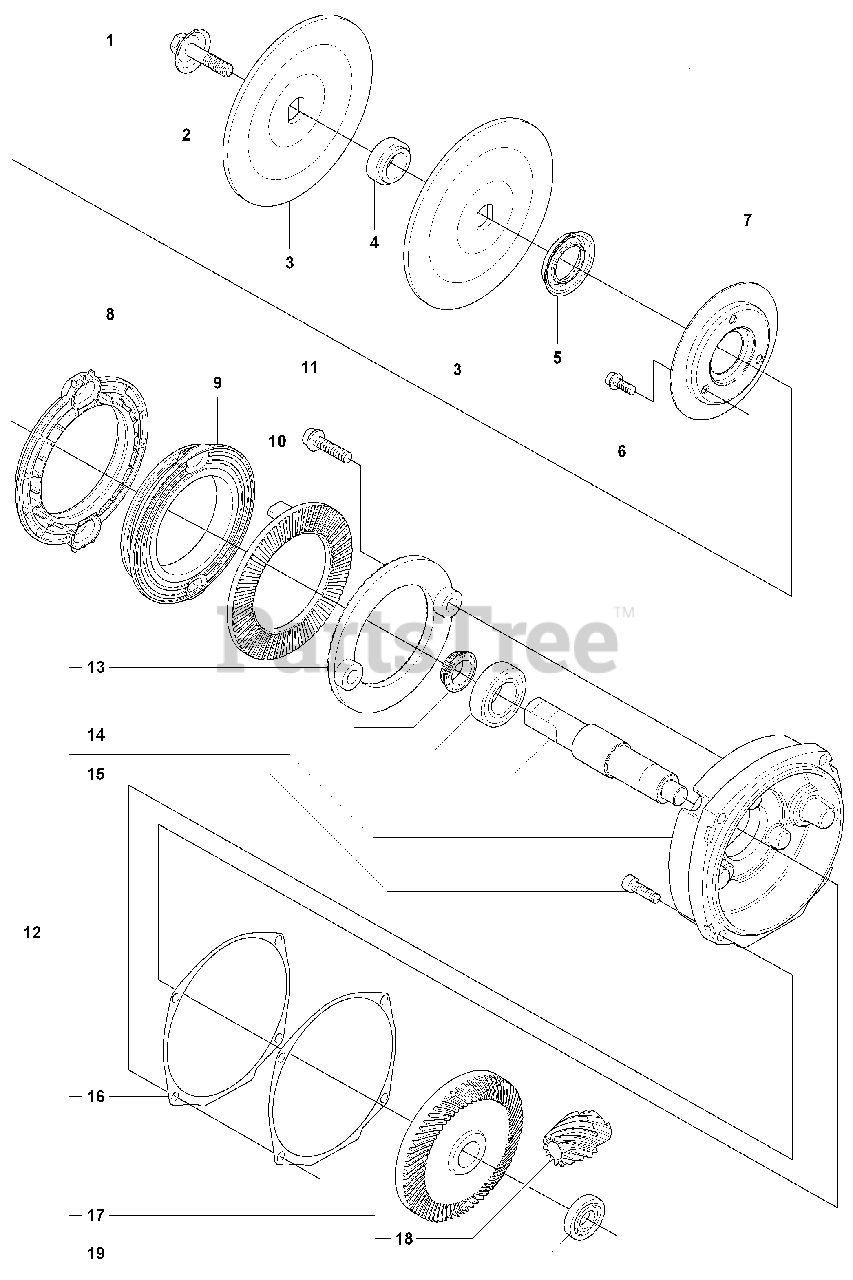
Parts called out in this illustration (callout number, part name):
1	COLLAR SCREW
2	WASHER
3	FLANGE WASHER
4	BUSHING
8	SPACER
10	SCREEN PATTERN FLANG
11	SCREW
12	GEAR SET
13	SCREEN PATTERN FLANG
14	SHAFT
15	SCREW
16	GASKET
17	GEAR WHEEL
19	BALL BEARING
